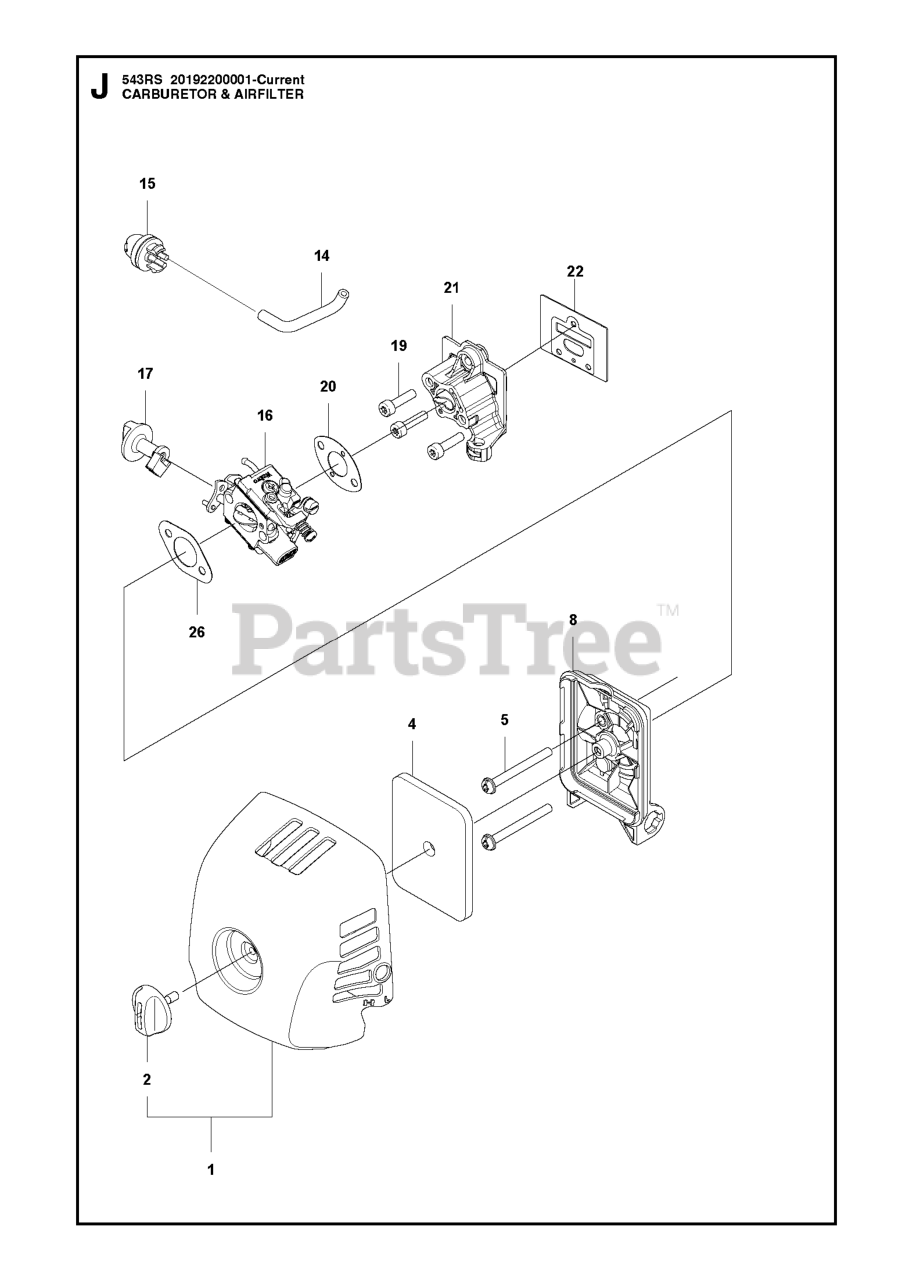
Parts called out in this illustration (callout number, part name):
2	TURNING KNOB GZ40N7
15	AIR PURGE BUBBLE
16	Carburetors
22	GASKET, INSULATOR
